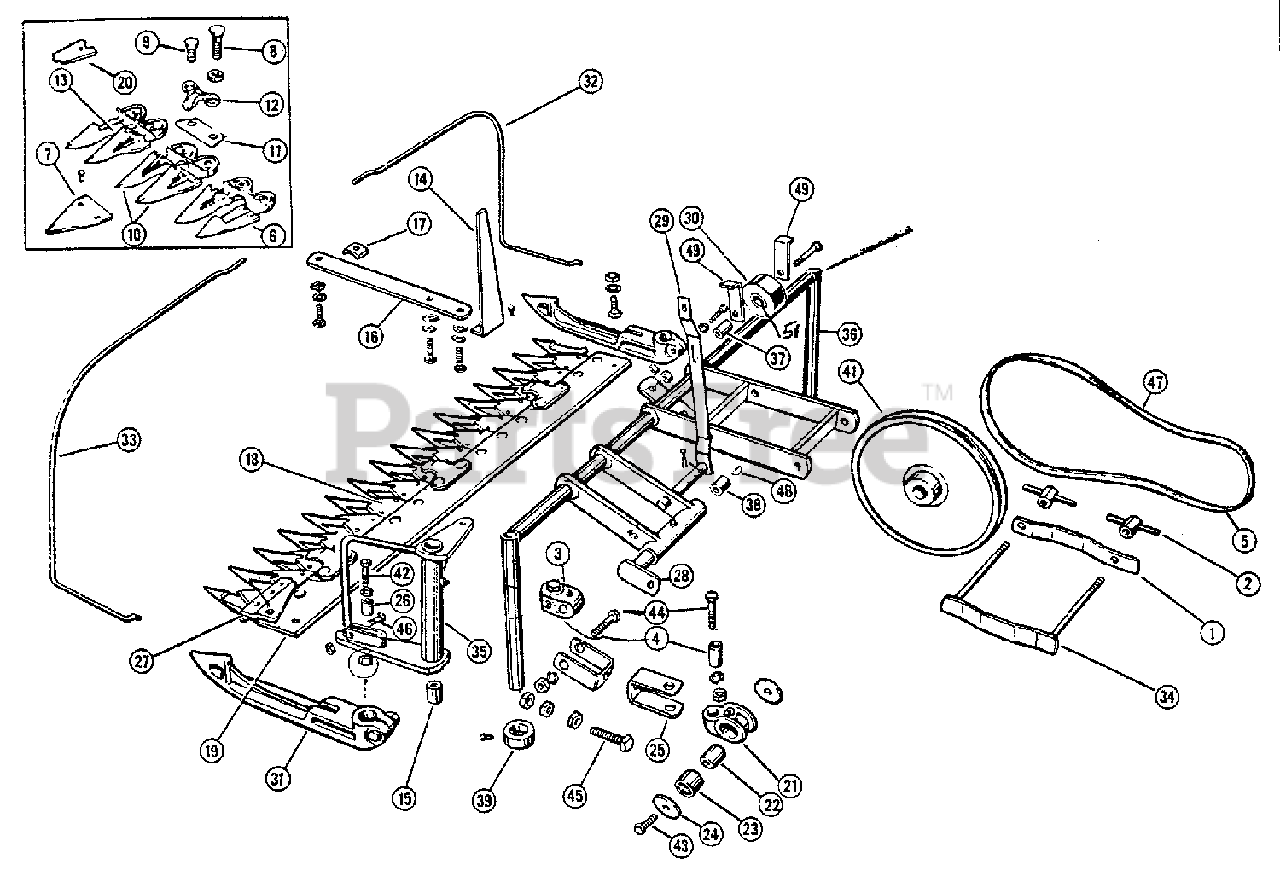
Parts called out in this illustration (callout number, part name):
1	HITCH, Side Plate
2	T-NUT, Complete
3	BLOCK, Pivot
4	BEARING, Pivot Block
5	BELT, 34" for L & F Series
6	GUARD, Left End
7	SICKLE SECTIONS
8	GUARD BOLT, Long
9	GUARD BOLT, Short
10	TWIN Guard
11	WEAR PLATE
12	SICKLE CLIP
13	RIGHT END GUARD
15	BUSHING, Bell Crank
16	BRACKET, Grass Finger
17	CLAMP, Grass Finger
18	SICKLE, Complete with Head
19	30" CUTTER BAR SLAB
20	PLATE, Ledger (With Rivet)
21	BEARING HOUSING, Pitman
22	BEARING, Pitman
23	BEARING, Needle (Pitman)
24	PITMAN BEARING, Washer
25	CLEVIS, Pitman
26	BUSHING, Sickle Head
27	SICKLE HEAD ONLY
28	CRANK SHAFT ASSEMBLY
29	LEVER, Idler
30	PULLEY, Idler
31	SICKLE BAR SHOE
32	GRASS FINGER, Right
33	GRASS FINGER, Left
34	CLAMP, Hitch
35	SICKLE BELL CRANK
36	FRAME, Sickle Bar
37	BUSHING, Idler Pulley
38	BUSHING, Bearing Housing
39	COLLAR, Set
42	SICKLE HEAD BOLT, 3/8-24 x 1/2
43	CRANK PIN BOLT, 3/8-24 x 2
44	PIVOT BLOCK BOLT, 3/8-24 x 2
45	PITMAN Mch BOLT, 7/16-14 x 1-1/2
46	ADJUSTMENT BOLT, 1/4-20 x 1-1/4
47	BELT, 38" For V & H Series
48	KEY, Woodruff, 3/16 x 3/4
49	BELT, Guide
